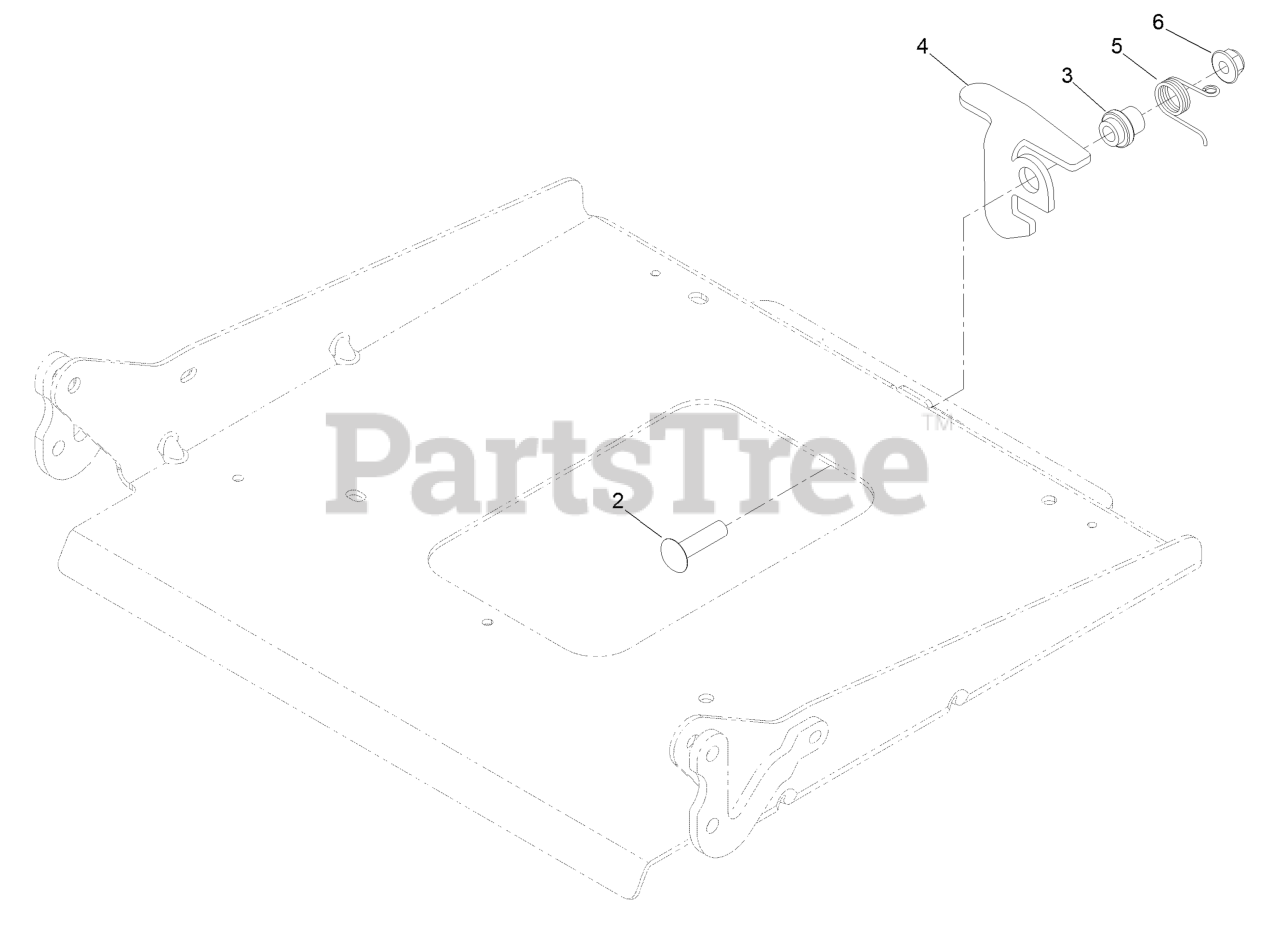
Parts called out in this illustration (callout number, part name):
2	SCREW-CARR
3	BUSHING-LATCH, SEAT
4	LATCH-CATCH, SINGLE
5	SPRING-TORSION, LATCH
6	NUT-HF, NI
